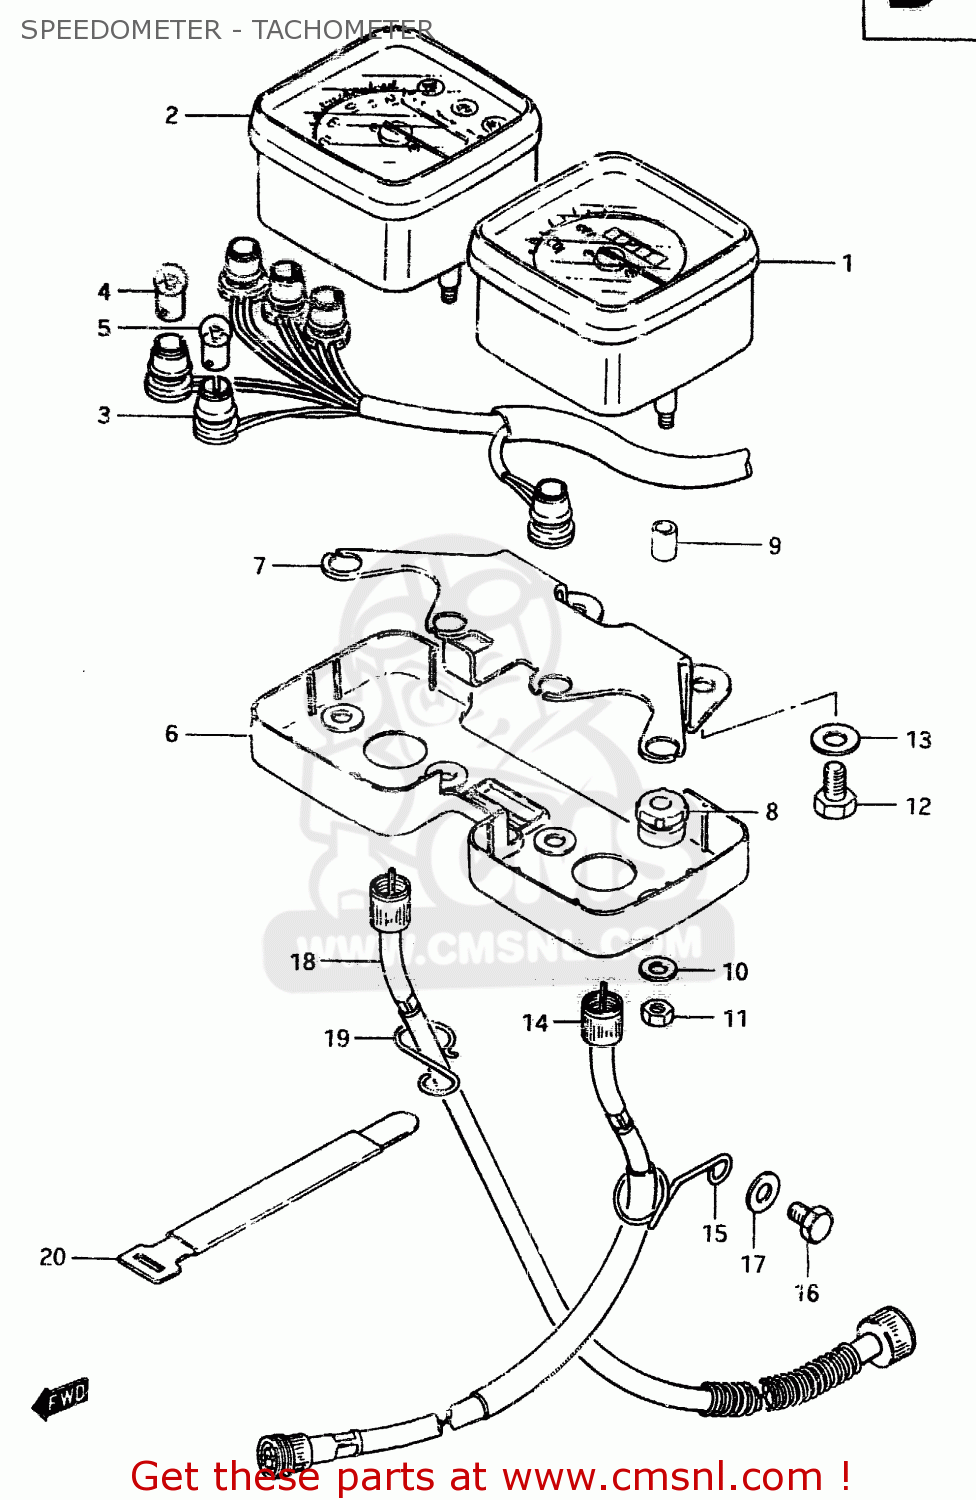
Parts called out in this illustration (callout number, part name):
1	SPEEDOMETER (KILO)
2	TACHOMETER
3	SOCKET
4	BULB(6V1.7W,STANLEY,A61A)
5	BULB(6V/3W)
6	COVER,METER UNDER
7	BRACKET
8	CUSHION,METER
9	SPACER
10	WASHER,METER
11	NUT
12	BOLT 8X12
13	WASHER
14	CABLE, SPEEDOMETER
15	CLIP
16	BOLT
17	WASHER
18	CABLE ASSY,TACHOMETER
19	CLAMP
20	CLAMP
